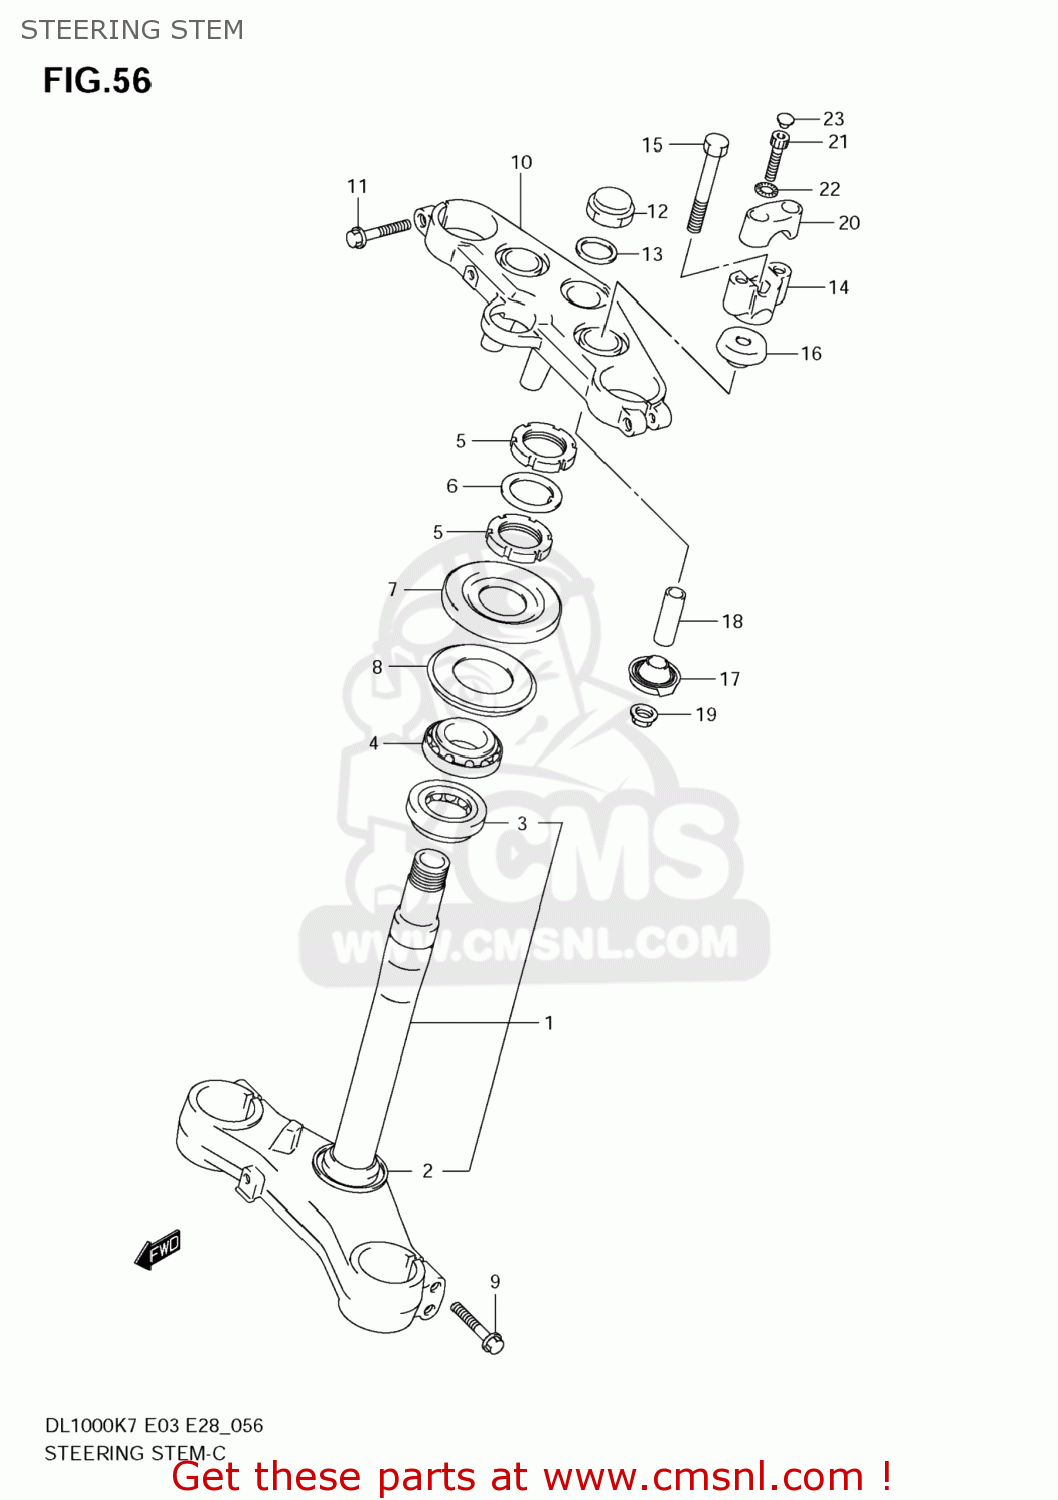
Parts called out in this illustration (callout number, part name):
1	STEM,STEERING
2	SEAL,STEERING LWR
3	BEARING(30X55X17)
4	BEARING(30X55X17)
5	NUT,STEERING STEM
6	WASHER,STEERING STEM
7	COVER,STEERING UPR
8	SEAL,STEERING LWR
9	BOLT
10	HEAD,STEERING STEM
11	BOLT
12	NUT
13	WASHER
14	HOLDER,HANDLE UNDER
15	BOLT,HANDLE HOLDER(10X70)
16	CUSHION,RUBBER UPR
17	RUBBER,LWR
18	SPACER
19	NUT
20	HOLDER,HANDLE UPR
21	BOLT
22	WASHER
23	CAP(OD:11)
